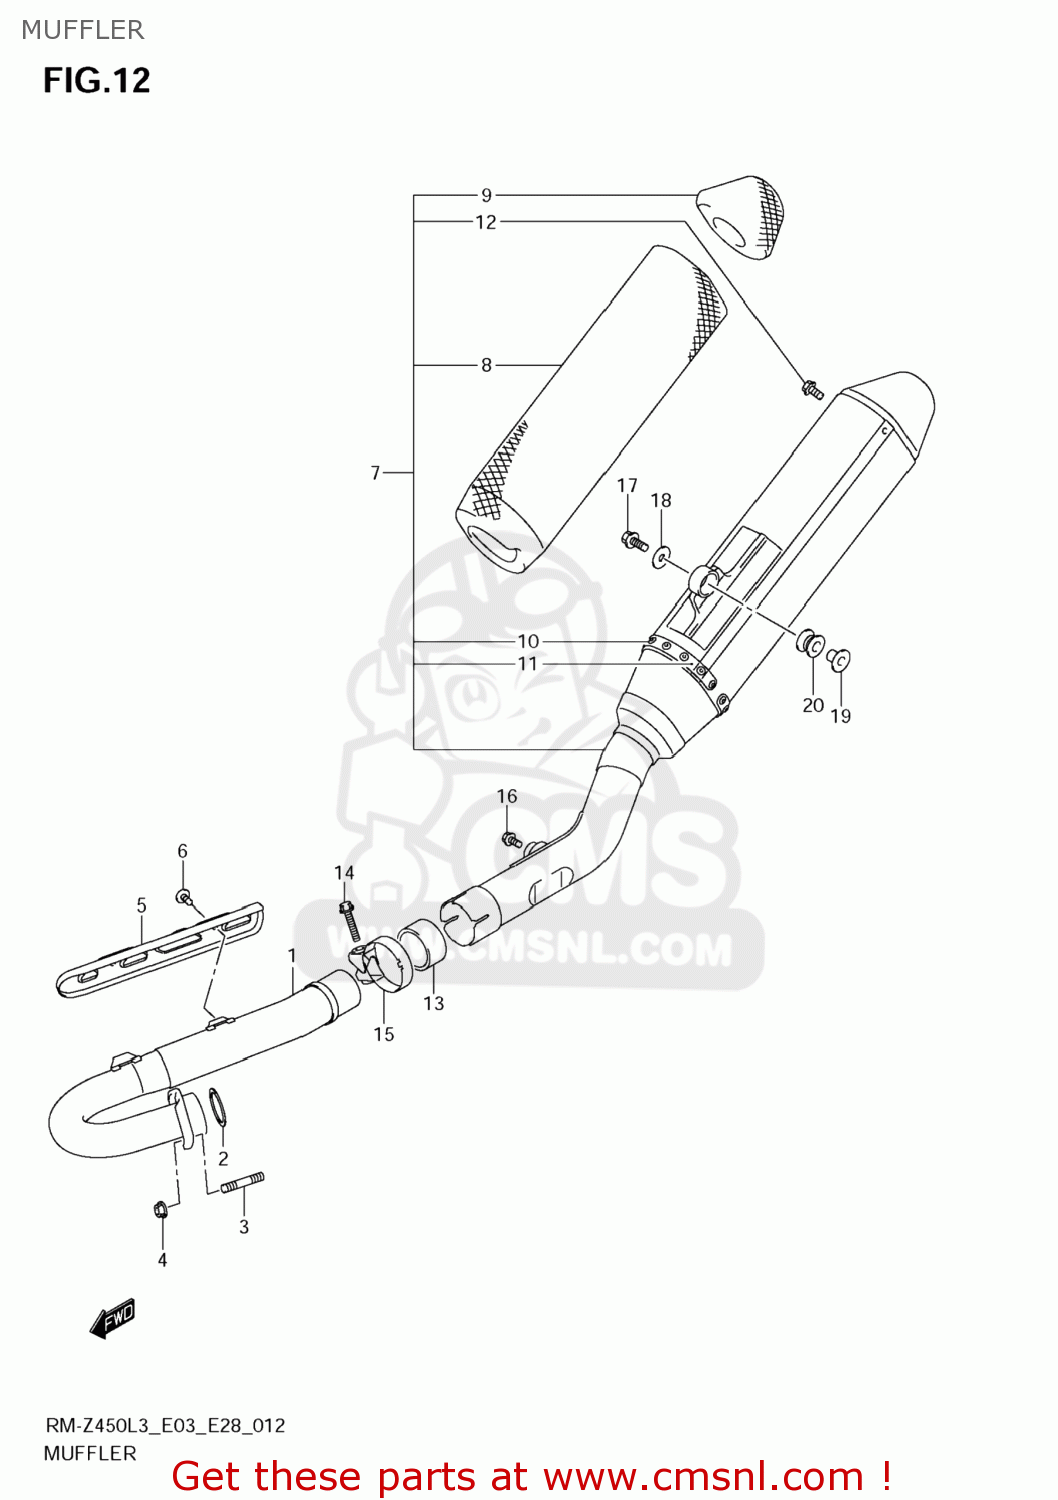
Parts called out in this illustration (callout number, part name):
1	PIPE,EXHAUST
2	GASKET,EXHAUST PIPE (NAS)
3	BOLT,STUD
4	NUT
5	COVER,EXHAUST PIPE
6	BOLT(6X8)
7	BODY,MUFFLER
8	SILENCER,MUFFLER
9	GLASS WOOL,MUF TAIL
10	RIVET,MUFFLER
11	BAND,MUFFLER
12	BOLT
13	CONNECTOR,MUFFLER
14	BOLT(8X35)
15	CLAMP,CONNECTOR
16	BOLT(8X20)
17	BOLT(8X35)
18	WASHER(8.5X26X1.6)
19	SPACER(8.6X12X18.5)
20	CUSHION
